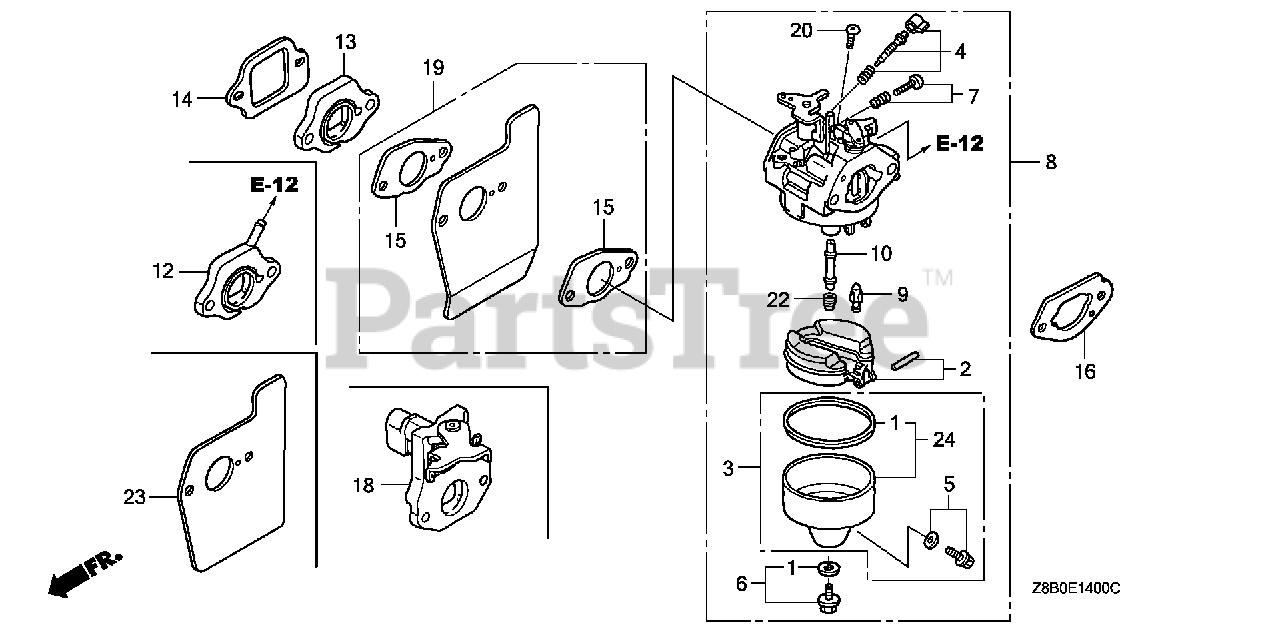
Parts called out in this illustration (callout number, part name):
1	GASKET SET
3	CHAMBER SET, FLOAT
5	SCREW SET, DRAIN
6	SCREW SET
7	SCREW SET (THROTTLE STOP)
8	CARBURETOR ASSY. (BB62W A)
8	CARBURETOR ASSY. (BB62W B)
9	VALVE, FLOAT
10	NOZZLE, MAIN
13	INSULATOR, CARBURETOR
14	GASKET, INSULATOR
15	GASKET, CARBURETOR
16	GASKET, CARBURETOR
19	GUIDE, AIR
20	SCREW, PAN (5X6)
22	JET, MAIN (#60)
22	JET, MAIN (#62)
22	JET, MAIN (#65)
23	GUIDE, AIR
24	CHAMBER SET, FLOAT
